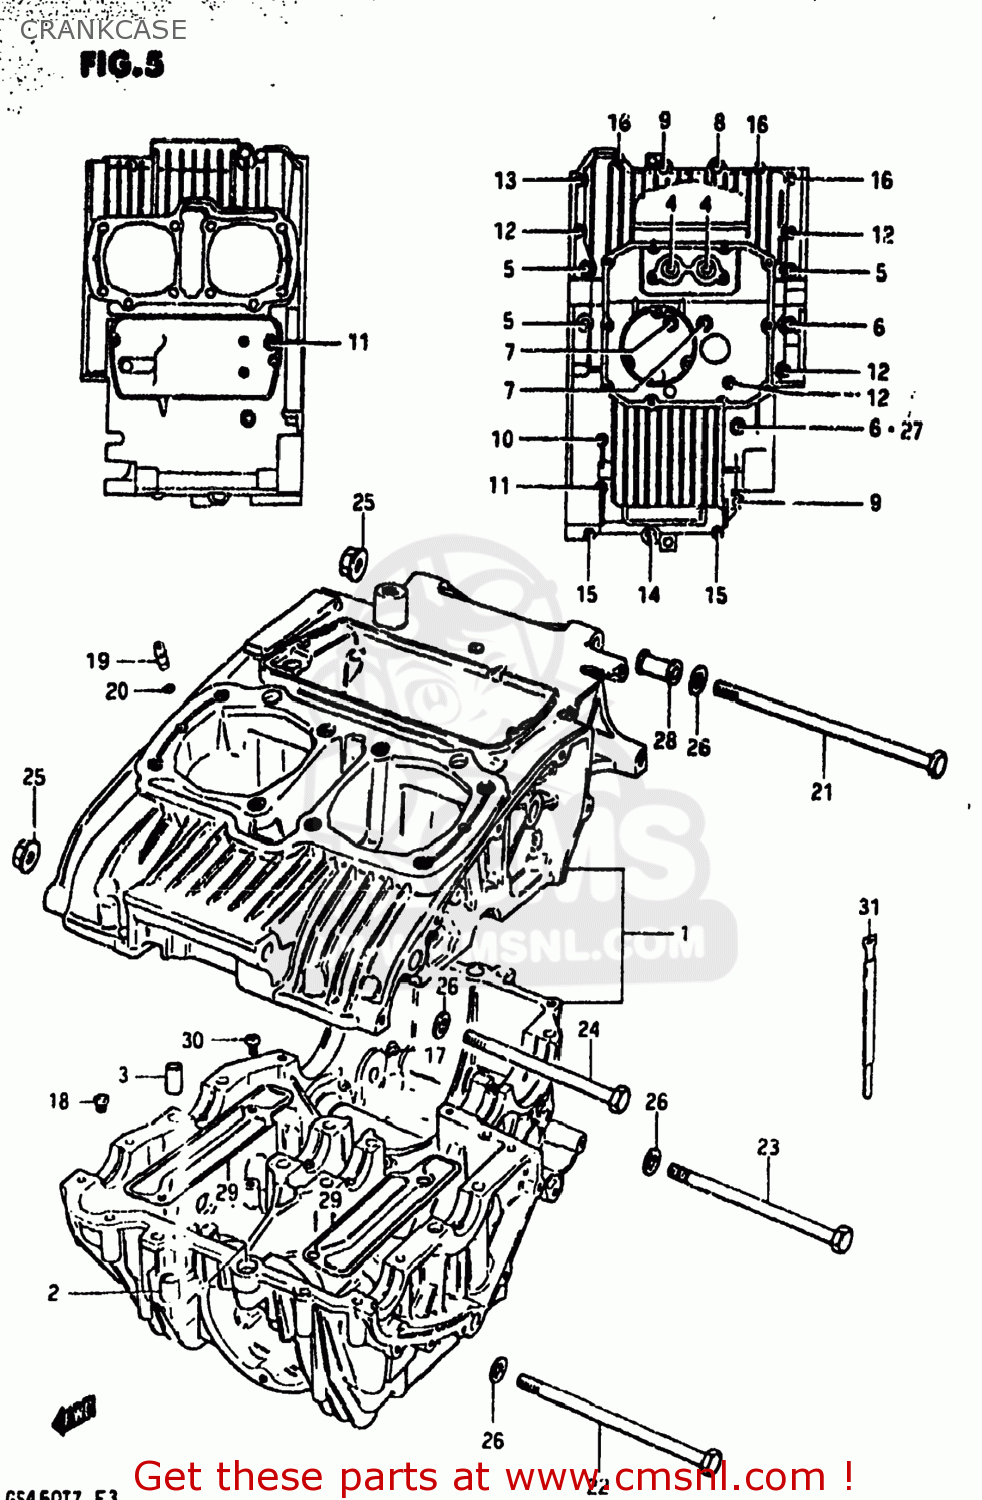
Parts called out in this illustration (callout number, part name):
1	CRANKCASE ASSEMBLY
2	PIN(10.4X13X22)
3	PIN (11X20)(SUS)
4	BOLT
5	BOLT
6	BOLT
7	BOLT
8	BOLT 8X65
9	BOLT (8X45)
10	BOLT
11	BOLT
12	BOLT (6X90)
13	BOLT (6X70)
14	BOLT 6X65
15	BOLT ,6X50
16	BOLT,UNDER
17	JET
18	JET
19	JET
20	O RING(D:1.05,ID:3.1)
21	BOLT 10X250
22	BOLT(10X210)
23	BOLT 10X160
24	BOLT
25	NUT 10MM
26	WASHER
27	GASKET 8.2X14X1 (NAS)
28	SPACER,ENGINE MOUNT
29	PLATE,OIL SEPARATOR
30	SCREW
31	CLAMP
